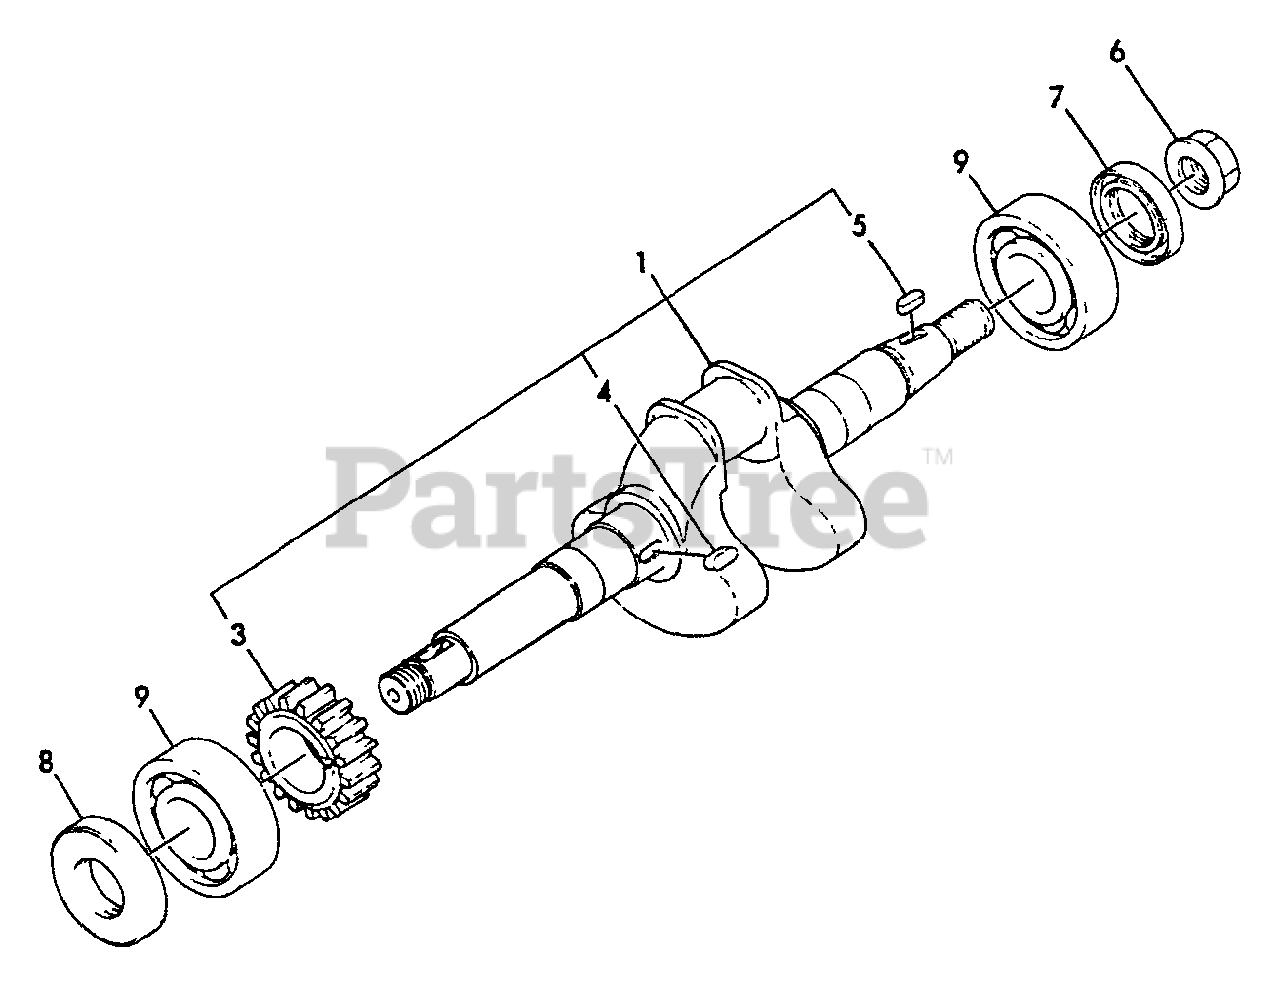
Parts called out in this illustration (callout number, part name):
1	CRANKSHAFT ASSY
3	GEAR, CRANKSHAFT
4	KEY - 4X10
5	KEY - 4X10
6	NUT - 12
7	SEAL, OIL
8	SEAL, OIL
9	BEARING, BALL - 6204C3
